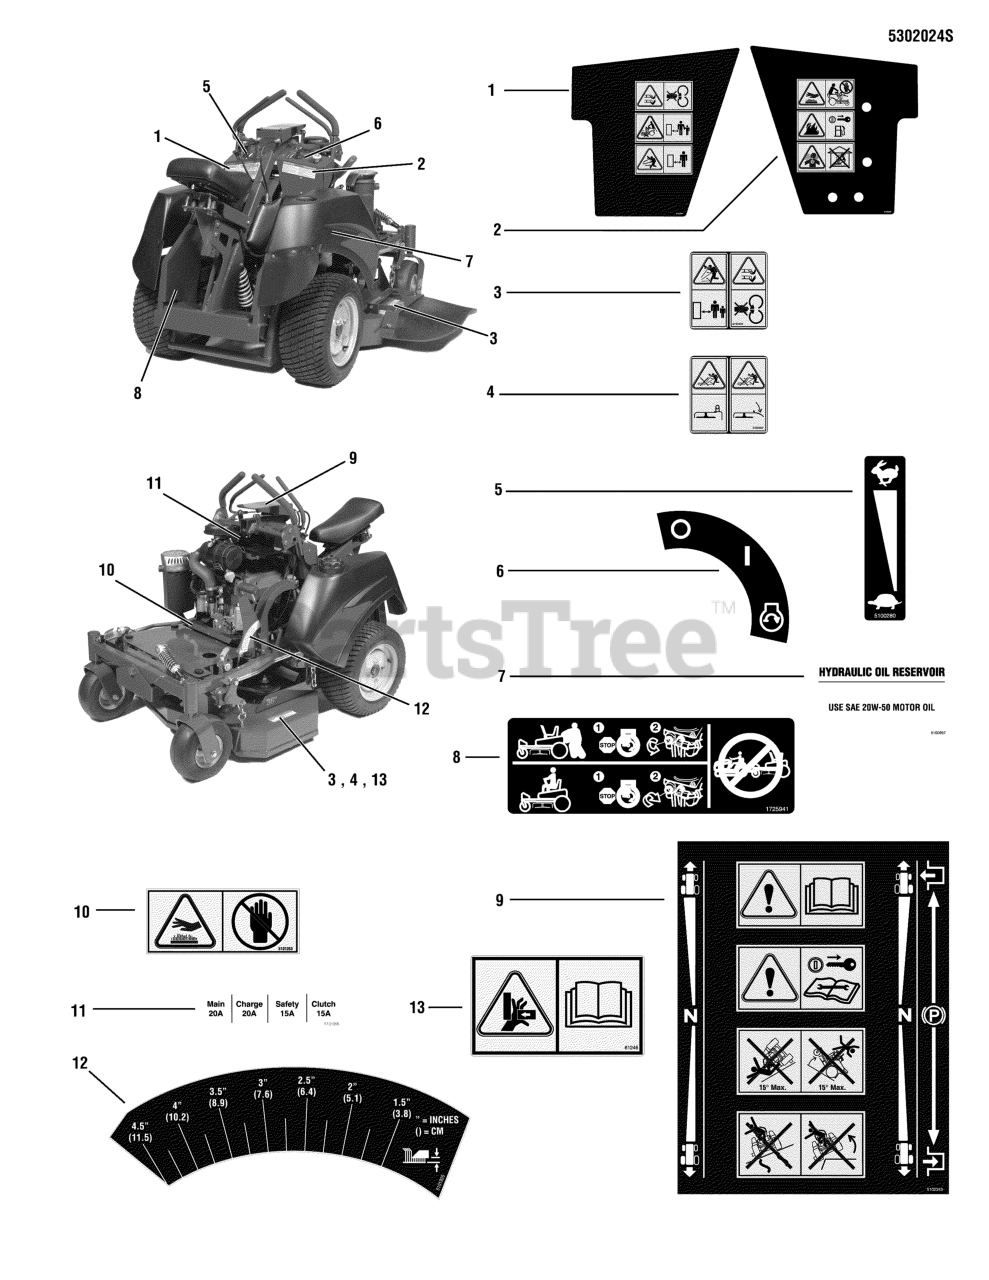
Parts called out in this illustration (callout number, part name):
1	DECAL, MAIN SAFETY, LH, CE
2	DECAL, MAIN SAFETY, RH, CE
3	DECAL, DANGER, MOWER DECK, ANSI EXP
4	DECAL, DANGER DISCHARGE ANSI EXPORT
5	DECAL, THROTTLE CONTROL
6	DECAL, IGNITION SWITCH
7	DECAL, OIL RESEVOIR
8	DECAL, CZT HYRDO RELEASE
9	DECAL, MAIN, CE
10	DECAL, PINCH POINT, CE
11	DECAL, FUSE LOCATION, EVOLUTION
12	DECAL, DECK HEIGHT, EVOLUTION
13	DECAL, HAND IN FLAME
